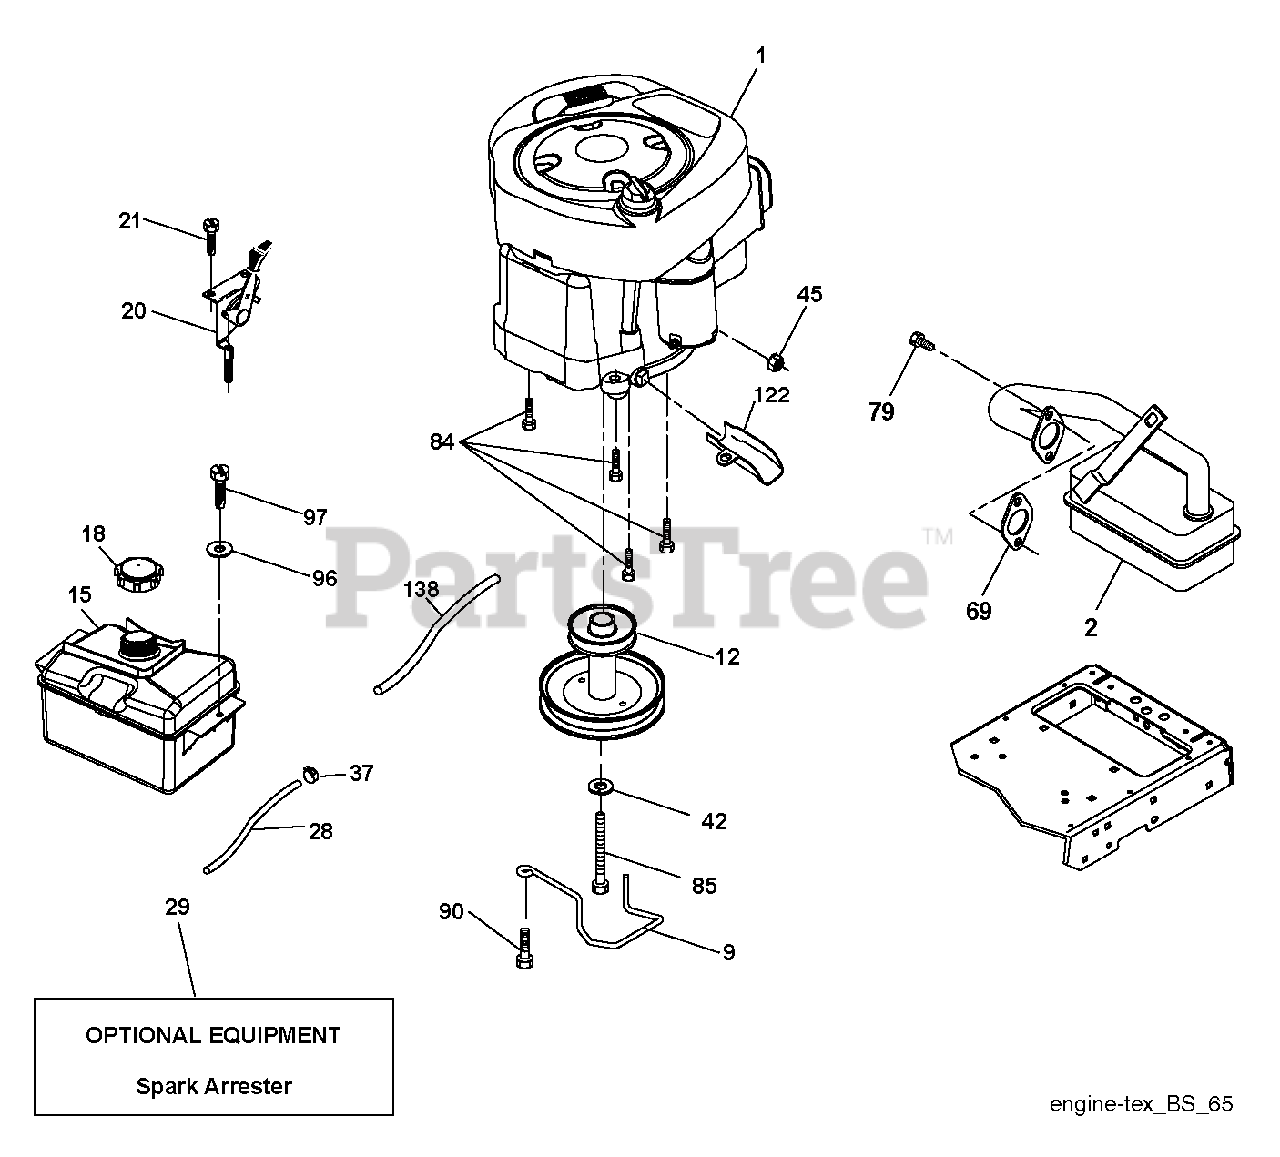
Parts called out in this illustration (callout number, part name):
2	MUFFLER.LT.BRIGGS.14HP.IC/OHV
9	KEEPER.BELT.ENGINE
12	Engine Pulley
15	TANK.ASM.1.5GAL.FRT.W/CAP.EPA
18	CAP.FUEL.2 WAY VENT
28	LINE.FUEL.20"FRONT.EMI
29	KIT.SPARK ARRESTOR(392390 B&S)
37	HOSE CLAMP
42	LOCKWASHER
45	NUT
79	SCREW.SOCKET HD.5/16-1
84	SCREW.3/8-16
85	BOLT HEX 7/16-20X4-1/4"
90	SCREW 3/8-16X1
96	WASHER
97	SCREW HEXWSHR 1/4-20X3/4
122	EXTENSION DRAIN OIL
138	RP PURGE LINE
